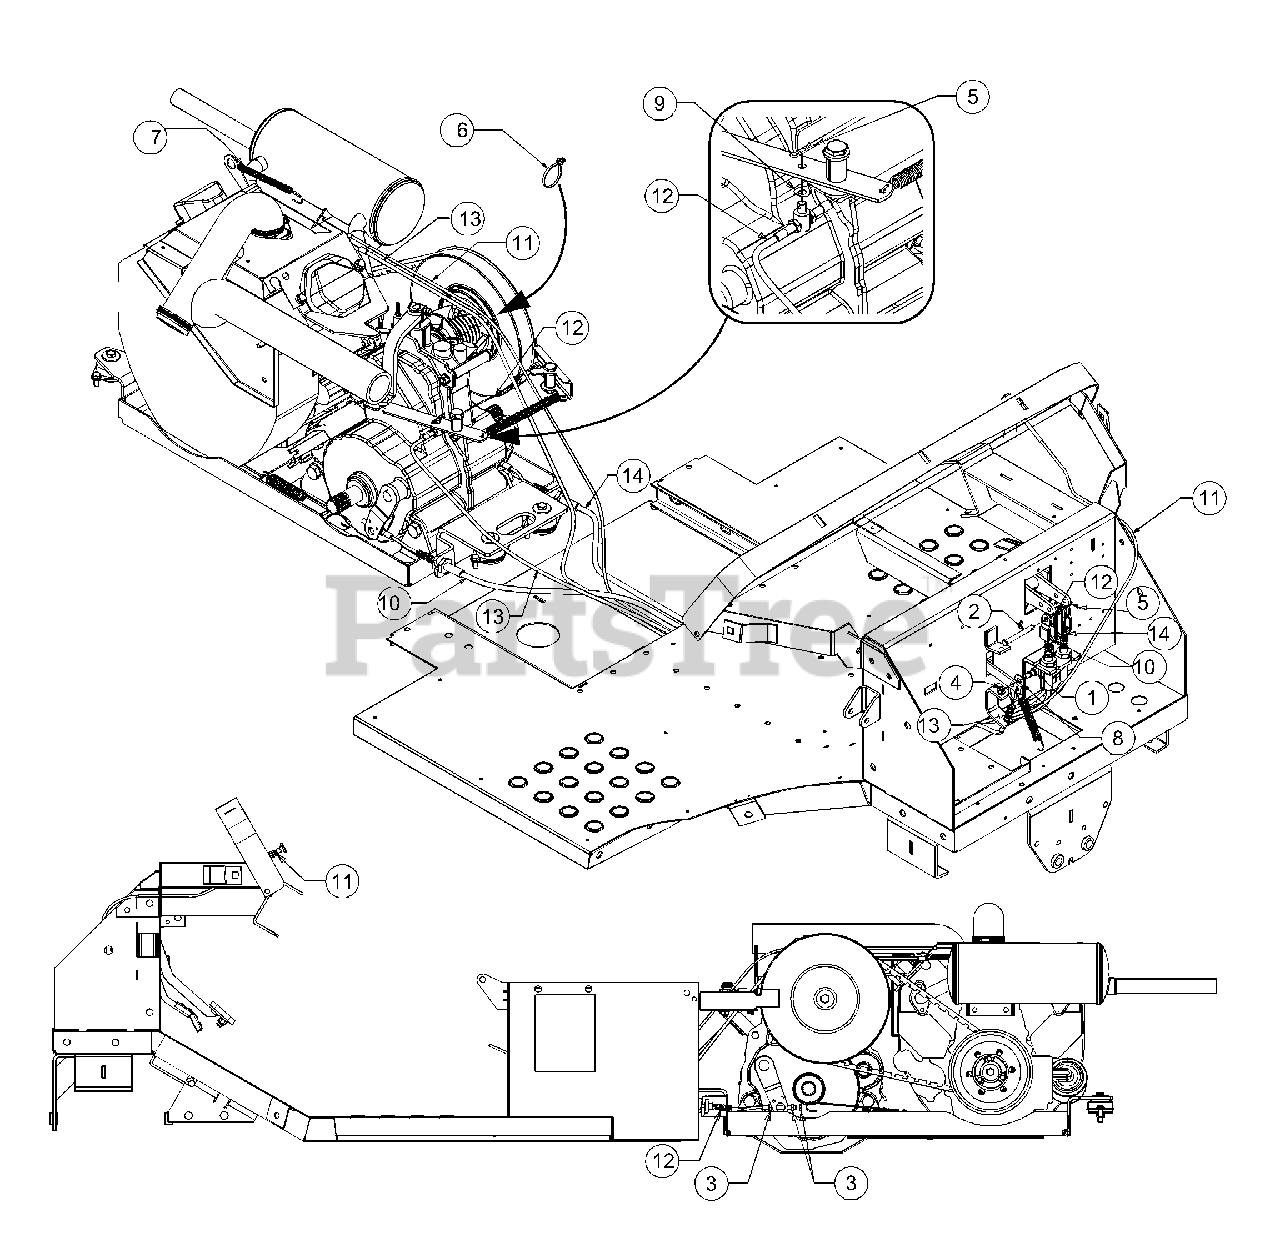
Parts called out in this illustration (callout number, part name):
1	Screw, Shoulder, .375 x .375
2	Pin, Clevis, 5/16 x 2.5
3	Nut, Jam, 5/16-24, Gr5
4	Nut, Hex Lock, 5/16-18
5	Pin, Cotter, .072 x 1.13
6	Cable Tie, Tree Mount
7	Extension Spring
8	Washer, .349 x .879 x .063
9	Washer, Spring, .317 x .879 x .063
10	Cable, Control, Brake
11	Cable, Control, Choke
12	Cable, Control, Clutch Brake
13	Cable, Control, Throttle
14	Cable, Control, Brake
